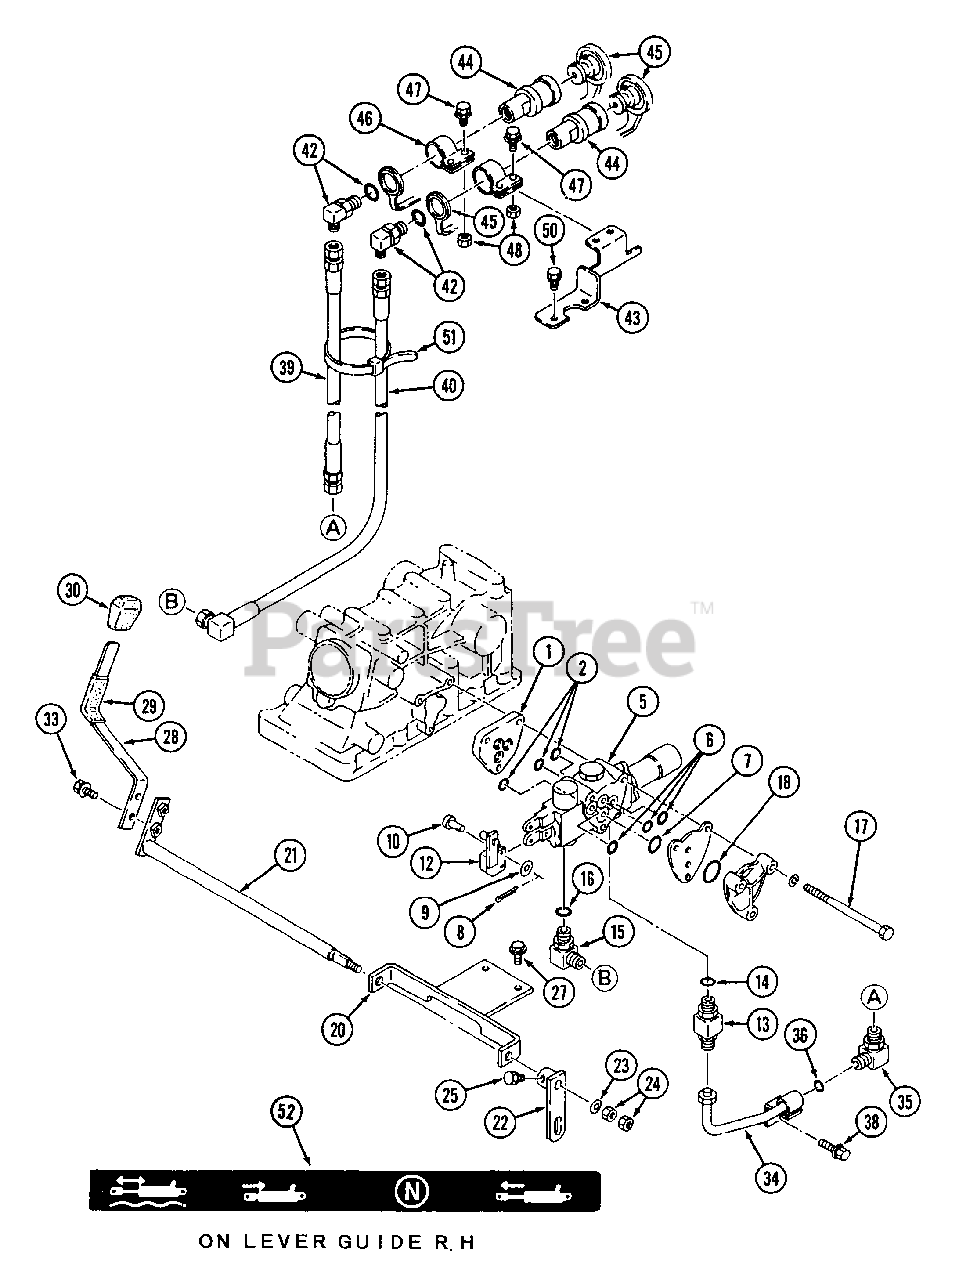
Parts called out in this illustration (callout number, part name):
5	Body
6	O-Ring
8	Pin, Split
13	Body (Nipple)
15	Adapter
28	Lever
34	Pipe Press. Ass'y.
35	Adapter
44	Coupling
46	Clamp, Coupler
52	Label, Aux. Valve
